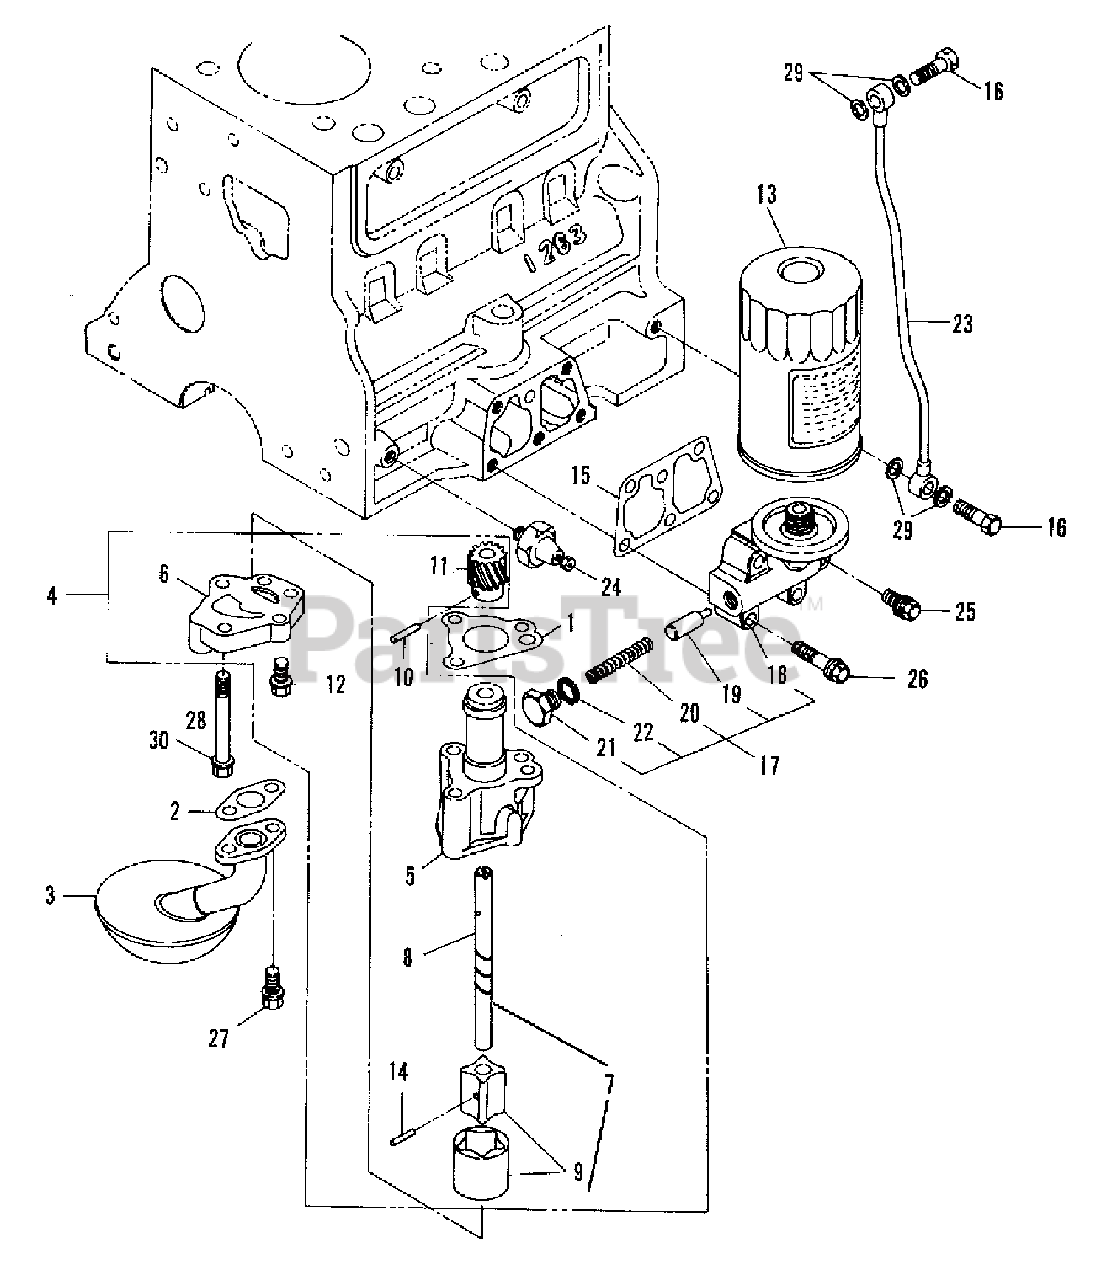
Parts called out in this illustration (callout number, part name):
1	GASKET, oil pump
2	GASKET, oil suction tube
3	TUBE ASSEMBLY, suction
4	PUMP ASSEMBLY (Incl. Items 5 thru 12 & 14)
5	BODY (Refer to PLUMP ASSEMBLY)
7	SHAFT ASSEMBLY, (Incl. Items 8, 9, 14)
9	ROTOR SET, inner & outer
10	PIN, dowel, gear
12	CAPSCREW, M6 x 20 w/lockwasher
13	FILTER ASSEMBLY, lube oil
14	PIN, dowell, rotor
16	BOLT, M10 x 28 hollow
17	HOUSING ASSEMBLY, oil control (Incl. Items 18 thru 22)
18	HOUSING (Refer to HOUSING ASSEMBLY)
19	INSERT, rellief valve
20	SPRING, relief valve
23	TUBE, lube oil
24	SWITCH, oil pressure
25	CAPSCREW, M8 x 22 w/washer, lockwasher
26	CAPSCREW, M8 x 40 w/washer, lockwasher
27	CAPSCREW, M8 x 20 w/lockwasher
28	CAPSCREW, M8 x 75 w/lockwasher
30	LOCKWASHER, M8
